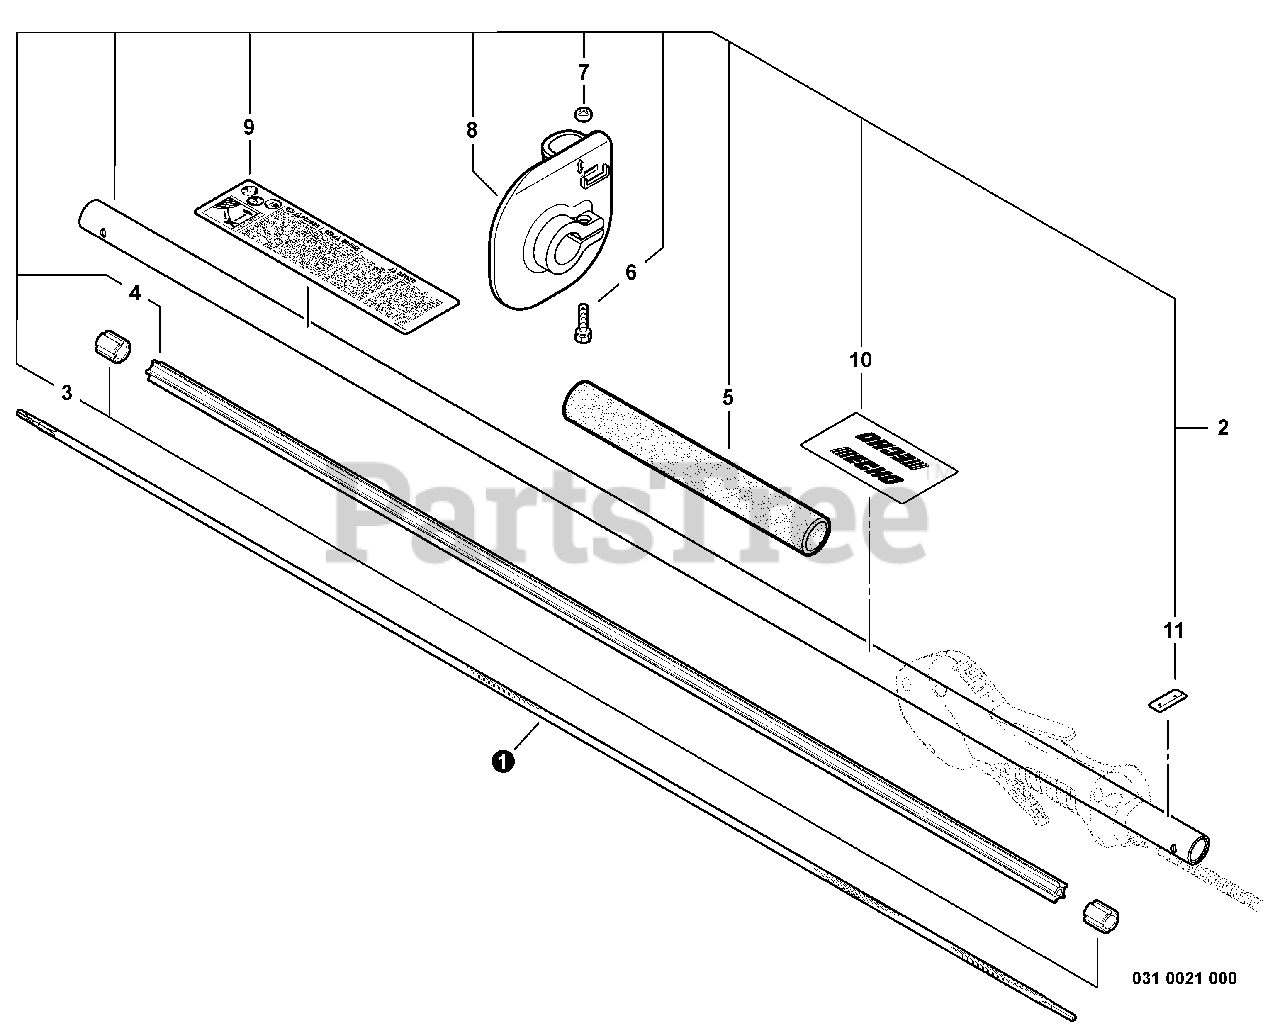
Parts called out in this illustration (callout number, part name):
1	DRIVESHAFT - FLEXIBLE L= 1522
2	MAIN PIPE ASSY
4	LINER, FLEXIBLE 21.6×1420
5	GRIP, HANDLE
6	BOLT 5×20
7	NUT M5
8	GUARD, HAND
9	LABEL, CAUTION
10	LABEL, HANDLE LOCATION
11	LABEL - ALIGNMENT
